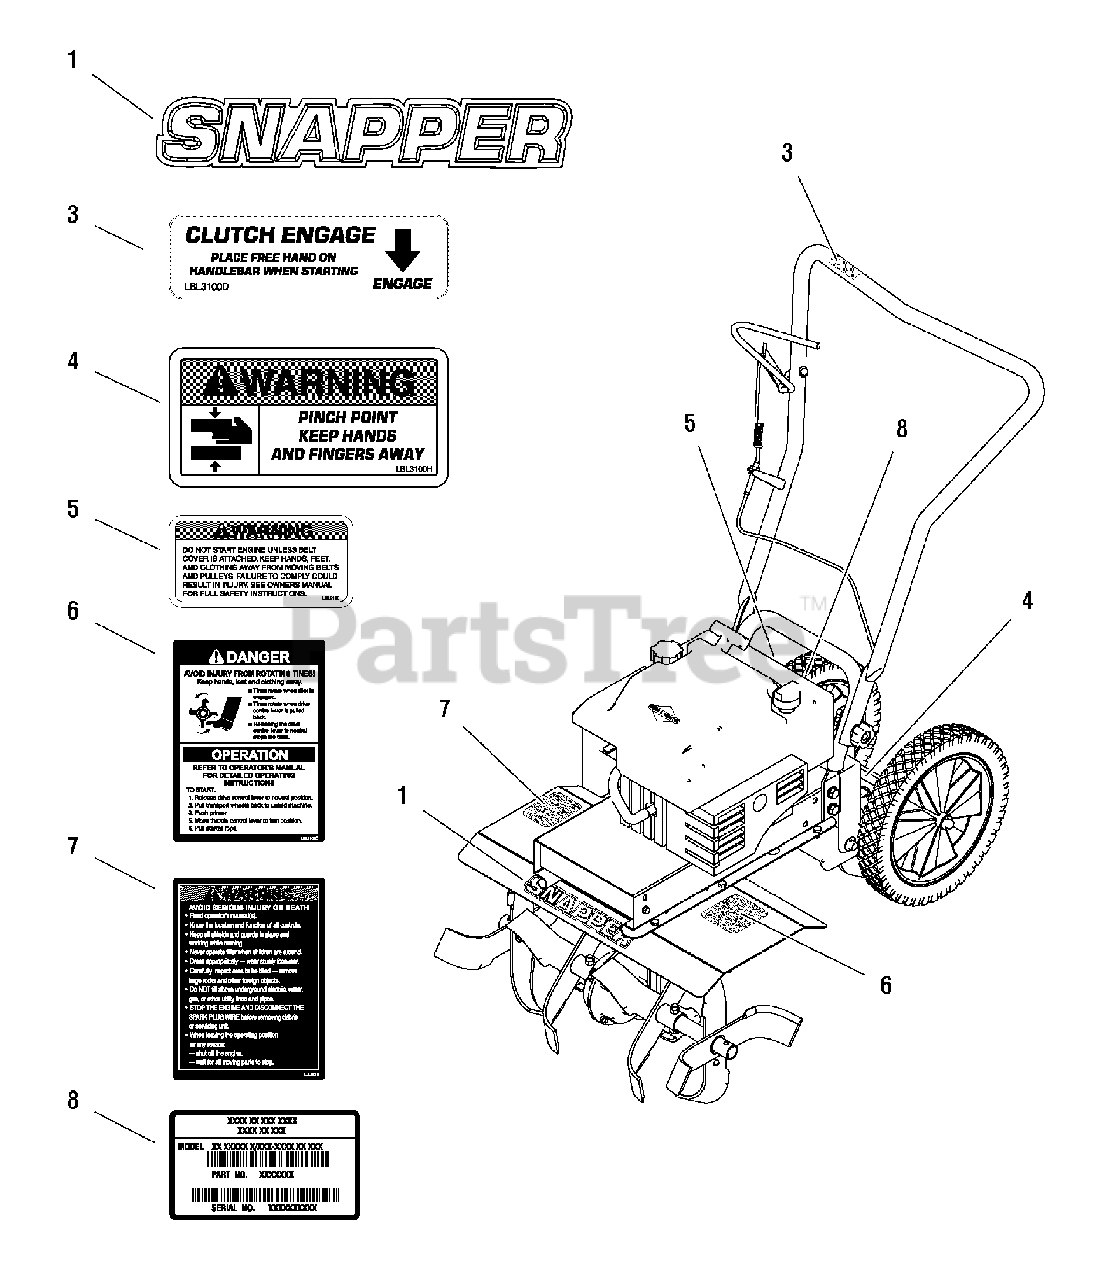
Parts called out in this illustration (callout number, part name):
1	DECAL, Snapper
2	DECAL SHEET, Common Warning Roticul Tillers
3	* DECAL, Clutch Engage
4	* DECAL, Warning Pinch Point
5	* DECAL, Warning, Belt Cover
6	* DECAL, Hood, Operator Instructions Label
7	* DECAL, Warning, Serious Injury
8	** DECAL, Serial Number
